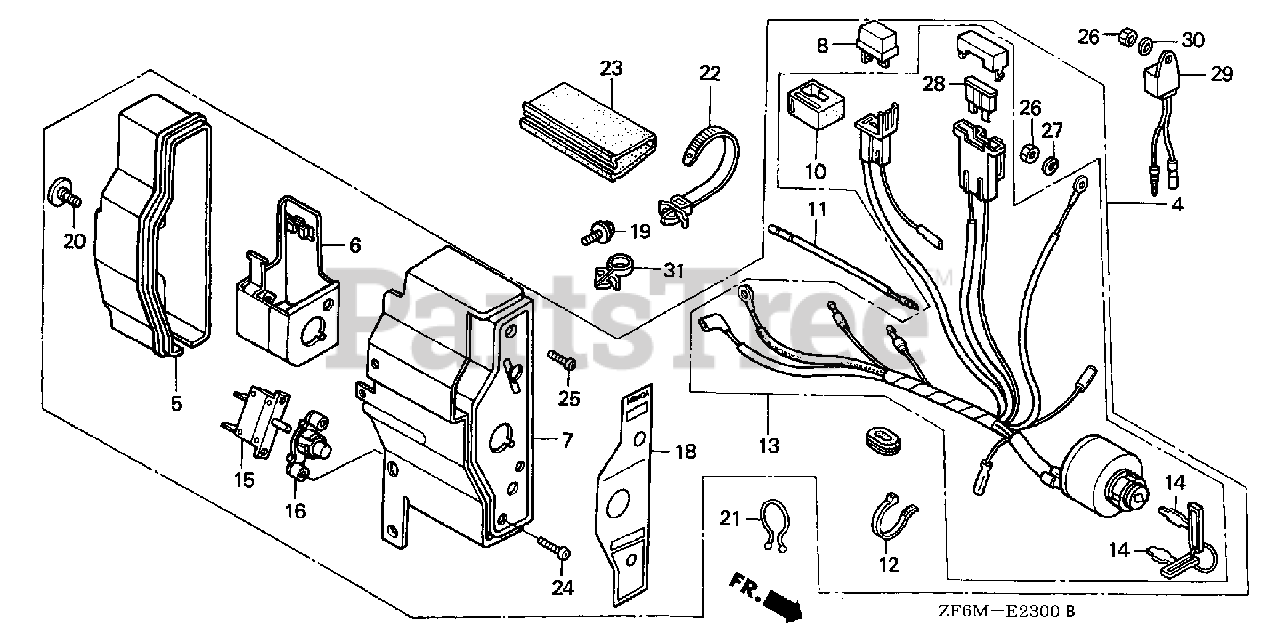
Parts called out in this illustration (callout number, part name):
4	BOX ASSY., CONTROL (EXTERNAL-ALERT/3A) *R8* (BRIGHT RED)
5	CASE, CONTROL
6	BRACKET, CASE MOUNTING
7	PANEL, CONTROL *R8* (BRIGHT RED)
8	RECTIFIER ASSY., SILICON (STANLEY)
10	SUSPENSION, CONNECTOR
11	SUB-HARNESS
12	BAND
13	SWITCH ASSY., COMBINATION
14	KEY
15	PROTECTOR, CIRCUIT (3.5A)
16	LENS ASSY., PROTECTOR
18	PANEL, CONTROL BOX (EXTERNAL)
19	BOLT, FLANGE (6X12) (CT200)
20	SCREW, SPECIAL (6X12)
21	CLIP, PURSE LOCK
22	STRAP, CABLE (118MM) *NH1L* (BLACK)
23	TUBE, FASTENER (30)
24	SCREW, PAN (3X12)
25	SCREW, PAN (4X12)
26	NUT, HEX. (4MM)
27	WASHER, SPRING (4MM)
28	FUSE, BLADE (15A)
29	ALERT UNIT, OIL
30	WASHER, PLAIN (4MM)
31	HOLDER, STOP SWITCH WIRE
